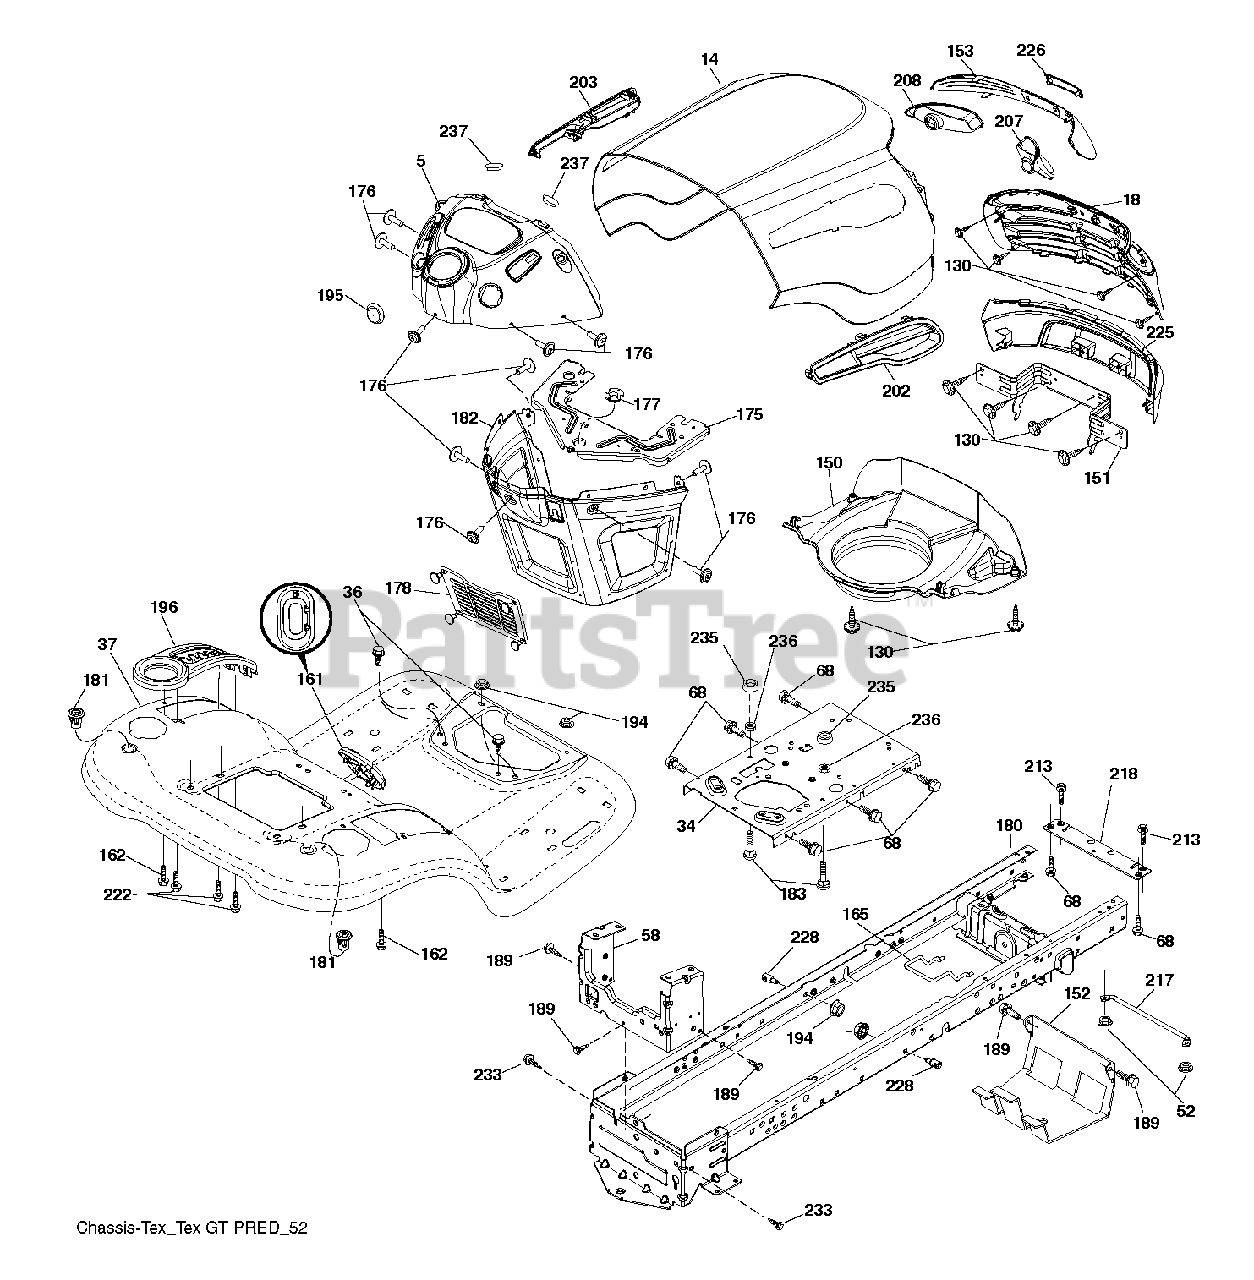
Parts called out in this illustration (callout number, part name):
36	SCREW 5/16"
52	LOCKNUT
58	DRAWBAR.UPPER.2PC,LRG.FENDER
130	SCREW.#10 X 0.750.BOS THREAD
152	SHIELD BROWNING
161	CONSOLE.FUEL.WINDOW.STGT.BLACK
162	SCREW.HI-LO.CONSOLE
165	SUPPORT.TANK.REAR.W/TE
175	PLATE.CROSSMEMBER.HUSQ
176	SCREW.#10-24X5/8.RN.QU
177	BUSHING,STEERING
178	CARGO.ASM.NET.TXGT.W/C
180	CHASS.WLDMNT.TL.12GA/2P.48/54
181	FEND/FTRST.PCH.CPH.NFW
182	DASH.LOWER.COMMON.12V.ADAPTOR
183	BOLT.5/16-18X1-1/4 FULL THD
189	SCREW
194	NUT LOCK HEX FLANGE 5/16-18
195	PLUG.HOLE.DASH.LOWER.12V.BLK
213	BOLT
217	ROD.PIVOT.HOOD
218	X-PIECE.HOOD.STOP.NON/
222	SCREW.1/4-20X5/8
228	STUD.FASTNER.W/ANTI-ROTATE
233	BOLT.SHOULDER
235	SPACER FENDER
236	NUT.CENTERLOCK.5/16-
237	PLUG.MOUNT.CARGO.BLK
